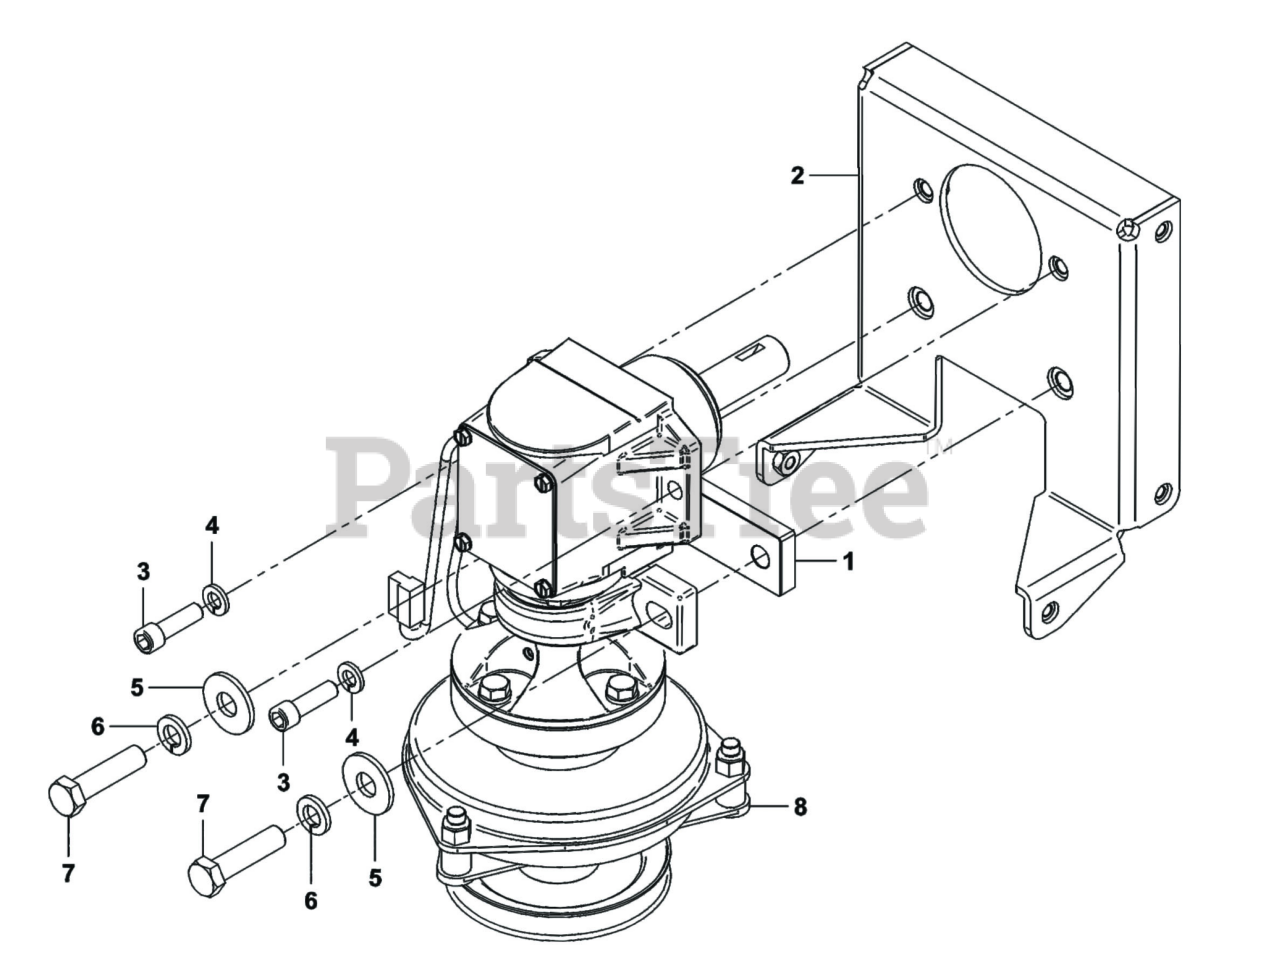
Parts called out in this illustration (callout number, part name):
1	SPACER PLATE
2	DRIVE MOUNT ASSEMBLY
3	SCREW 3/8"-16 X 1.25"
4	LOCK WASHER 3/8
5	FLAT WASHER 1/2"
6	LOCK WASHER 1/2"
7	SCREW 1/2"-13 X 2"
